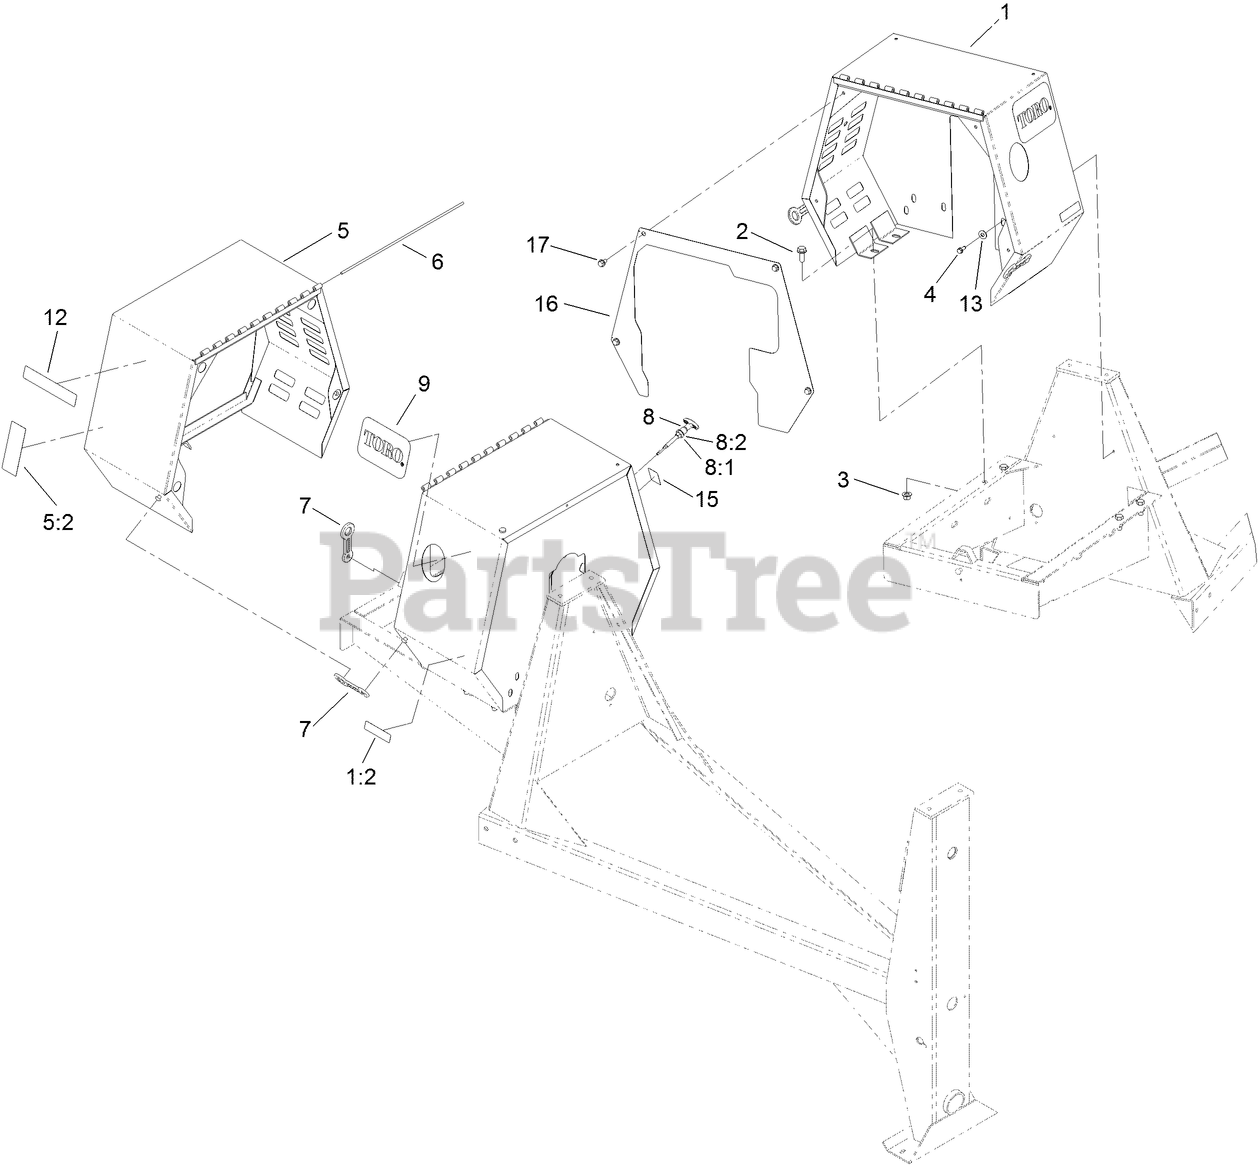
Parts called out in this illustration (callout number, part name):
1	COWL ASM
1:2	DECAL-ARRESTER, SPARK
2	SCREW-HHF
3	NUT-LOCK
4	SCREW-HWHTF
5	MOVABLE COWL ASM
5:2	DECAL-WARNING
7	LATCH-RUBBER
8	CABLE-THROTTLE, 125CM
8:1	NUT-JAM
8:2	WASHER-LOCK
9	DECAL
13	WASHER-FLAT
15	DECAL-THROTTLE, DIESEL
16	PLATE-DRIVE, GUARD
17	SCREW-HWH
